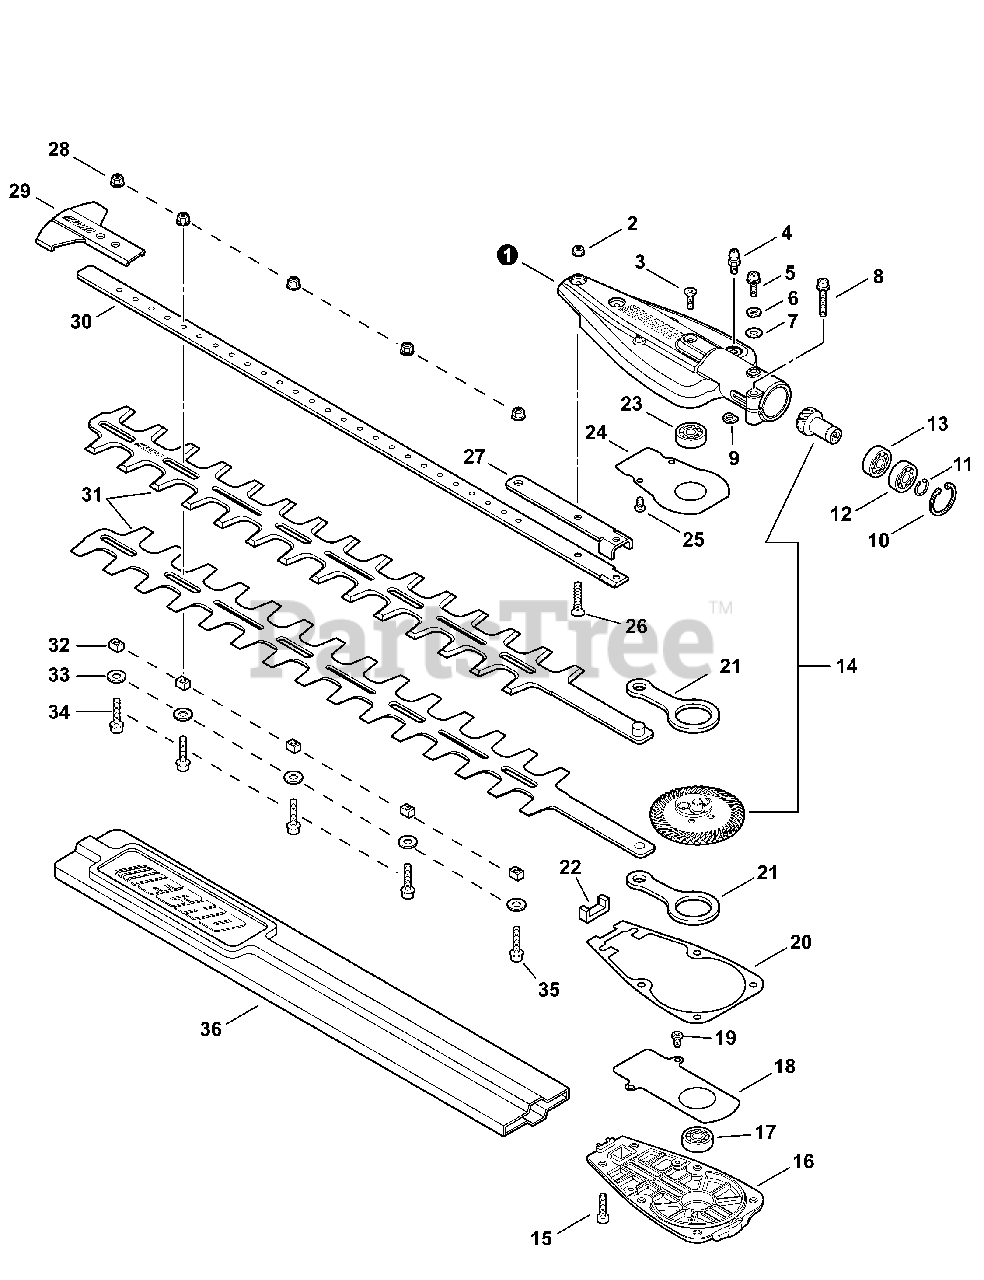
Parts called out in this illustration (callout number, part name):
1	HOUSING, GEAR CASE
2	NUT, FLANGE M5
3	SCREW 5×5/8" HD-SOCKET
4	FITTING, GREASE
5	BOLT, TORX 5×12
6	WASHER, SPRING 5
7	WASHER, FLAT 5.5×10×0.8
8	BOLT, TORX 5×25
10	RING, RETAINING Ø24
11	RING, SNAP Ø12
12	BEARING, BALL
13	BEARING, BALL 6901Z
14	GEAR SET
15	BOLT 5×12
16	COVER, GEAR CASE
17	BEARING, BALL 628ZZ
18	GASKET, GEAR CASE
19	SCREW 4×5
20	PLATE, WEAR
21	ROD, CONNECTING
23	BEARING, BALL 608ZZ
24	PLATE, WEAR
25	SCREW 4×5
26	SCREW 5×18
27	SUPPORT, BLADE
28	NUT, FLANGE M5
29	GUARD, TIP
30	SUPPORT, BLADE
31	CUTTER
32	GUIDE, BLADE 5
33	WASHER 5
34	BOLT 5×20
35	BOLT, FLANGE 5×22
36	SCABBARD
